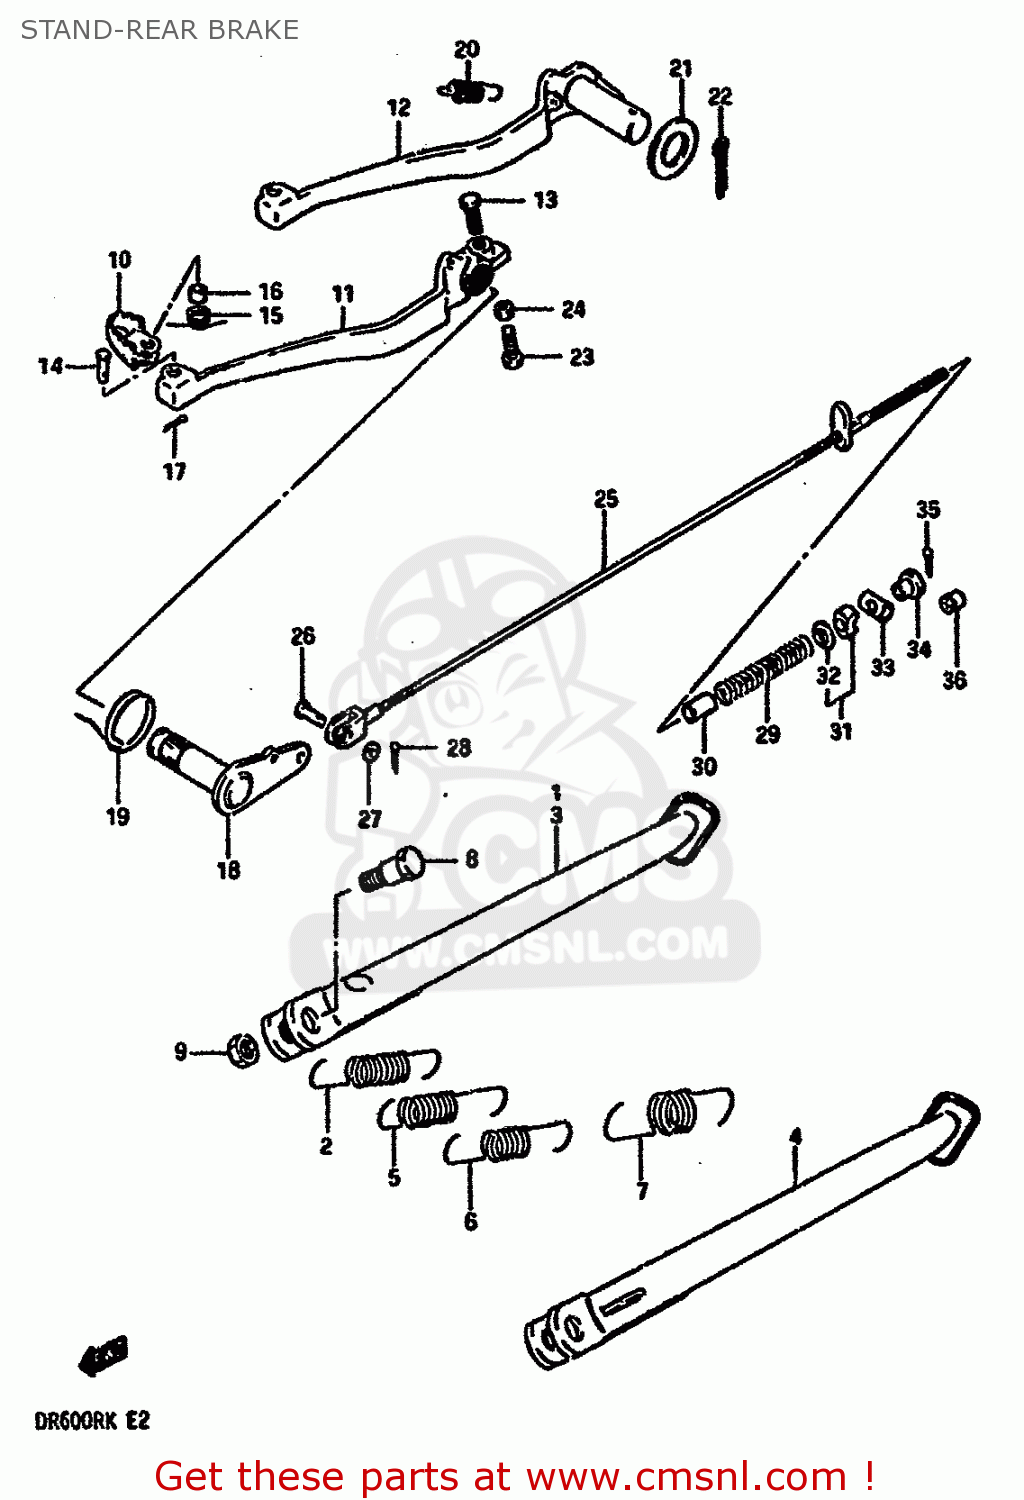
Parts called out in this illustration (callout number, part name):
1	STAND,PROP (BLUE)
2	SPRING
3	STAND,PROP (WHITE)
4	STAND, PROP (BLUE)
6	SPRING
7	SPRING
8	SPRING
9	BOLT L:30
10	NUT
11	PEDAL,BRAKE
12	ARM COMP,BRAKE PEDAL
13	BOLT
14	PIN
15	SPRING
16	SPACER(9.2X9X6.5)
17	PIN
18	ARM,BRAKE PEDAL ROD
19	SPRING
20	SPRING
21	WASHER (17.6X34X2)
22	COTTER PIN
23	BOLT(6X23)
24	NUT 6MM
25	CABLE,RR BRAKE
26	PIN(L:17.5)
27	WASHER, LOWER
28	PIN
29	SPRING
30	CUSHION,FR GRILLE,UPPER
31	CUSHION
32	WASHER
33	PIN,BRAKE CABLE ADJUSTER
34	NUT (6MM)
35	PIN
36	CAP
